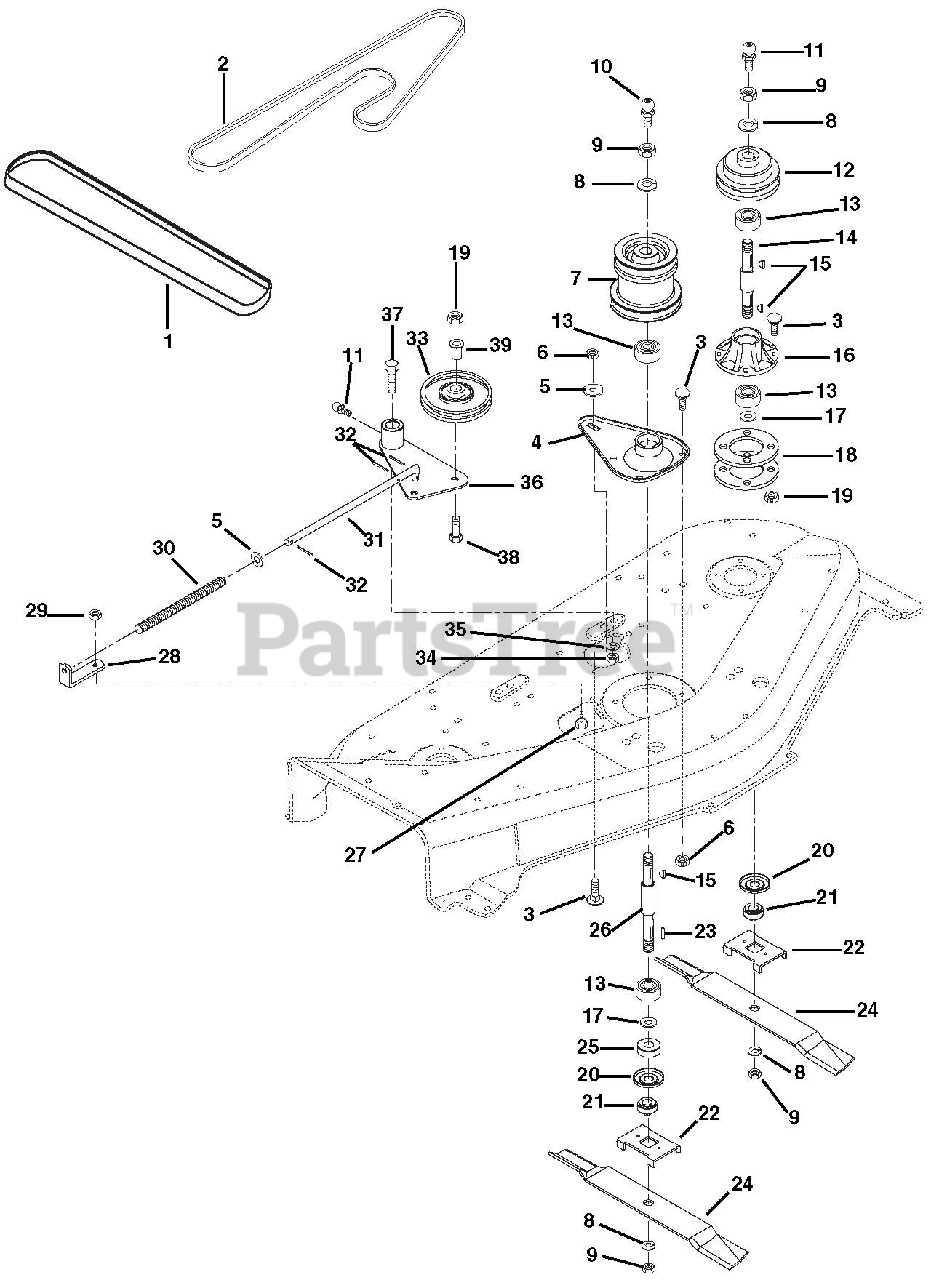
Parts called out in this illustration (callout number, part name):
1	V-BELT, HA-WRAPPED
2	V-BELT, HA-RAW EDGE
3	@BLT-RDHDSQNK .38-16X1.00 G5YZ
4	HOUSING, SPINDLE
5	@WSHR-FL-STL.406X.812X.065 YWZ
6	@NUT-LK-CTR .38-16 YWZC
7	SHEAVE, 48" DECK
8	@WSHR-LK .75X.188 REG YWZC
9	NUT-JAM .75-10 YWZC
10	FTG,LUBE 1/8
11	FTG-LUBE .25-28X.256 YWZC
13	BRG-BALL .750X1.781X.61
14	SPINDLE SHAFT W/ZERK
15	KEY-WDRF .188X.625X.25 SAE 61
16	SPINDLE HOUSING
17	WSHR-FL-STL .754X1.000X.032 YZ
18	SPACER, SPINDLE
19	@NUT-LK-TOP-FLG .38-16 YWZC
20	BEARING SLINGER
21	RETAINER HUB
22	BLADE TRAY 48
23	KEY-SQ .188X.625X.188 SAE 61
24	BLADE
25	WSHR-FL-STL .755X1.25X.125 YZ
26	SPINDLE SHAFT W/ZERK & KEY
27	@BLT-HEX .31-18X.50 GR5 YWZC
28	BRACKET
29	@NUT-LK-CTR .31-18 YWZC
30	SG-COMP .106X.63X 12.0 WLD 62
31	ROD-IDLER SPRING
32	@PIN-CTR .09X.75 EXTPRSQCT YWZ
33	IDLER, PLASTIC, 4.00 X .50 ID
34	@NUT-LK-CTR .50-13 YWZC
35	WSHR-FL-STL .505X.880X.072 YWZ
36	IDLER ARM
37	@BLT-HEX .50-13X1.50 GR5 YWZC
38	BLT-BTHD .38-16X1.25 GR5
39	SPACER -FLANGED .390X.500X.781
